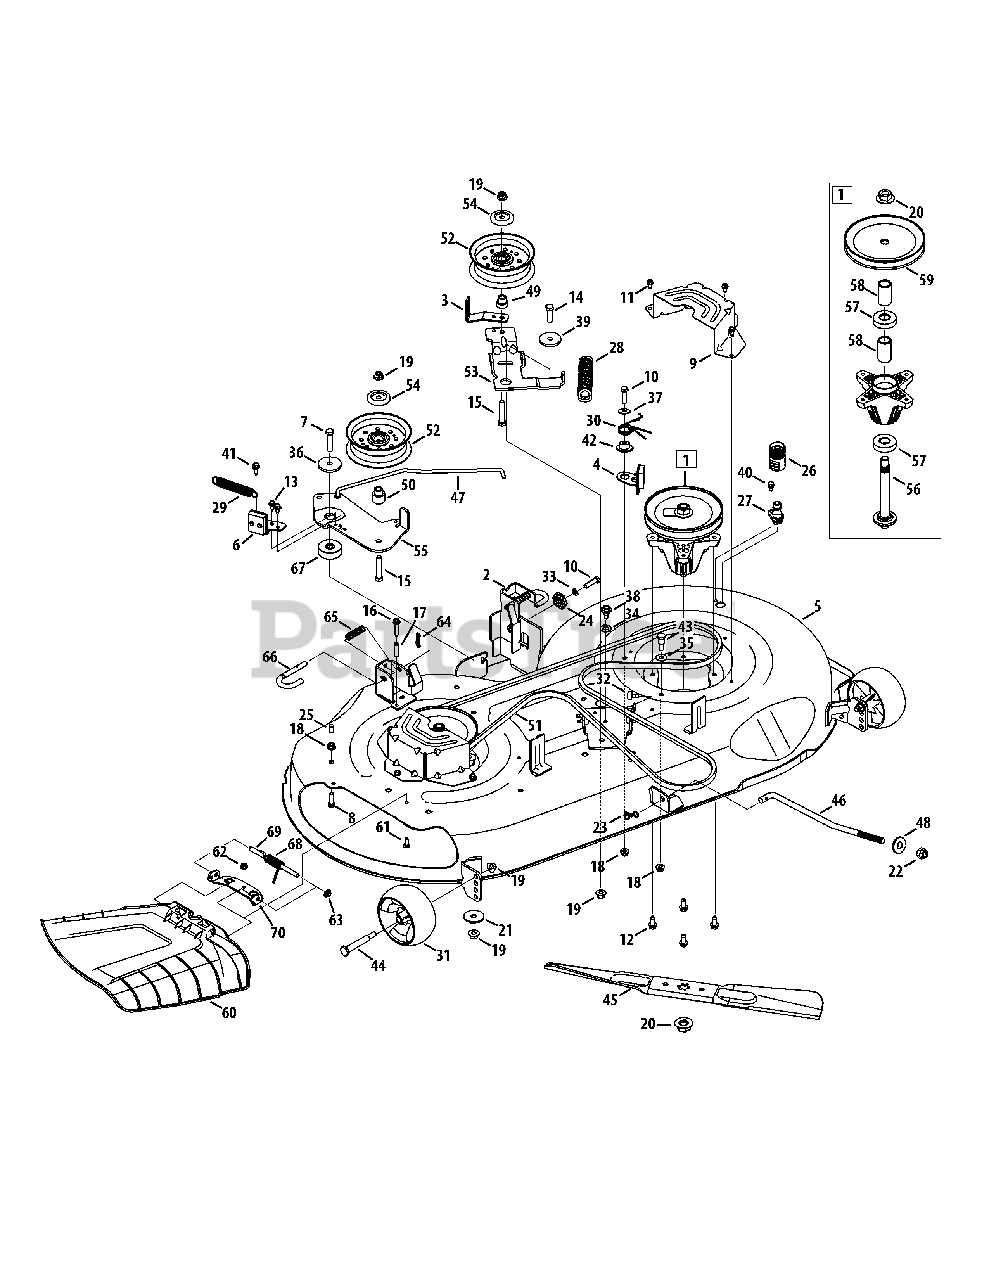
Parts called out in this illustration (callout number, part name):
1	Spindle Assembly, Pul 6.74 Dia
2	Bracket Assembly, Deck Hanger, LH
3	Belt Keeper
4	Brake Assembly, Deck, LH
5	Deck, 46t, 2w
6	Brake Assembly, Deck, RH
7	Hex Screw, 3/8-16 x 1.75
8	Hex Cap Screw, 5/16-18 x 1.00
9	Deck Belt Cover, 46
10	Hex Screw, 5/16-18, 1.25, Gr5, Std
11	Screw, Self-tapping, 1/4-20, 0.500
12	Screw, 5/16-18 x 0.750
13	Screw, M6-1 x .625
14	Hex Screw, 3/8-16 x 1.25
15	Hex Head Screw, 3/8-16 x 2.00
16	Screw, 1/4-20 x 1.25
17	Spacer, .260 x .375 x 1.030
18	Nut, Flange Lock, 5/16-18, Nylon
19	Nut, Flange Lock, 3/8-16, Nylon
20	Nut, Flange, 5/8-18
21	Flat Washer, .406 x 1.500 x .105
22	Flange Lock Nut, 1/2-13
23	Bow-Tie Cotter Pin
24	Gear, Deck Adjustment
25	Cap, .290 x .500
26	Water Nozzle Adapter
27	Deck Wash Nozzle
28	Spring, Extension, 1.05 X 6.346
29	Spring, Extension, .750 x .477
30	Torsion Spring, LH
31	Wheel, Deck, 5.0 Dia Ball
32	Bumper, .62 Dia X .3
33	Washer, Lock, 5/16, Regular Duty
34	Washer, Flat, .474 x .879 x .064
35	Washer, Flat, .343 X .880 X .062
36	Shoulder Spacer, .970 X .190
37	Flat Washer, .344 x 1.0 x .063
38	Shoulder Spacer, .43 x .29, 5/16-18
39	Shoulder Spacer, .8840 X .190
40	Shoulder Screw, 1/4-20 x 0.50
41	Shoulder Screw, .368 x .113 x 1/4-20
42	Shoulder Spacer, .75 x .145
43	Shoulder Screw, .437 Dia. X .54
44	Bolt, Shoulder, .496 x 2.50, 3/8-16
45	Blade, Cut, 23.25" 2-In-1
46	Rod, Lift, Deck, Medium
48	Pivot Cup, Deck List
49	Shoulder Spacer, Idler
50	Shoulder Spacer, Pivot Idler
51	Belt, V-Typ, A Sec
52	Pulley, Idler, 4.50"Dia
53	Bracket, Idler, 46" Lh
54	Pulley Cap
55	Deck Idler Bracket
56	Spindle Shaft, 6.05 LG.
57	Ball Bearing, .787ID X 1.85 ODX.551
58	Spacer, .792 X 1.060 X 1.860 LG
59	Deck Pulley, 6.74 DIA
60	Chute Deflector Assembly
61	Hex Cap Screw, 1/4-20 x .62
62	Nut, Flange Lock, 1/4-20, Nylon
63	Push Cap
64	Bow-Tie Cotter Pin, 72
65	Spring, Compression, .535 x 1.751
66	Rod, Deck Release
67	Spacer, .385 ID x 1.75 OD x .585
68	Spring, Torsion, .440 ID x 1.75
